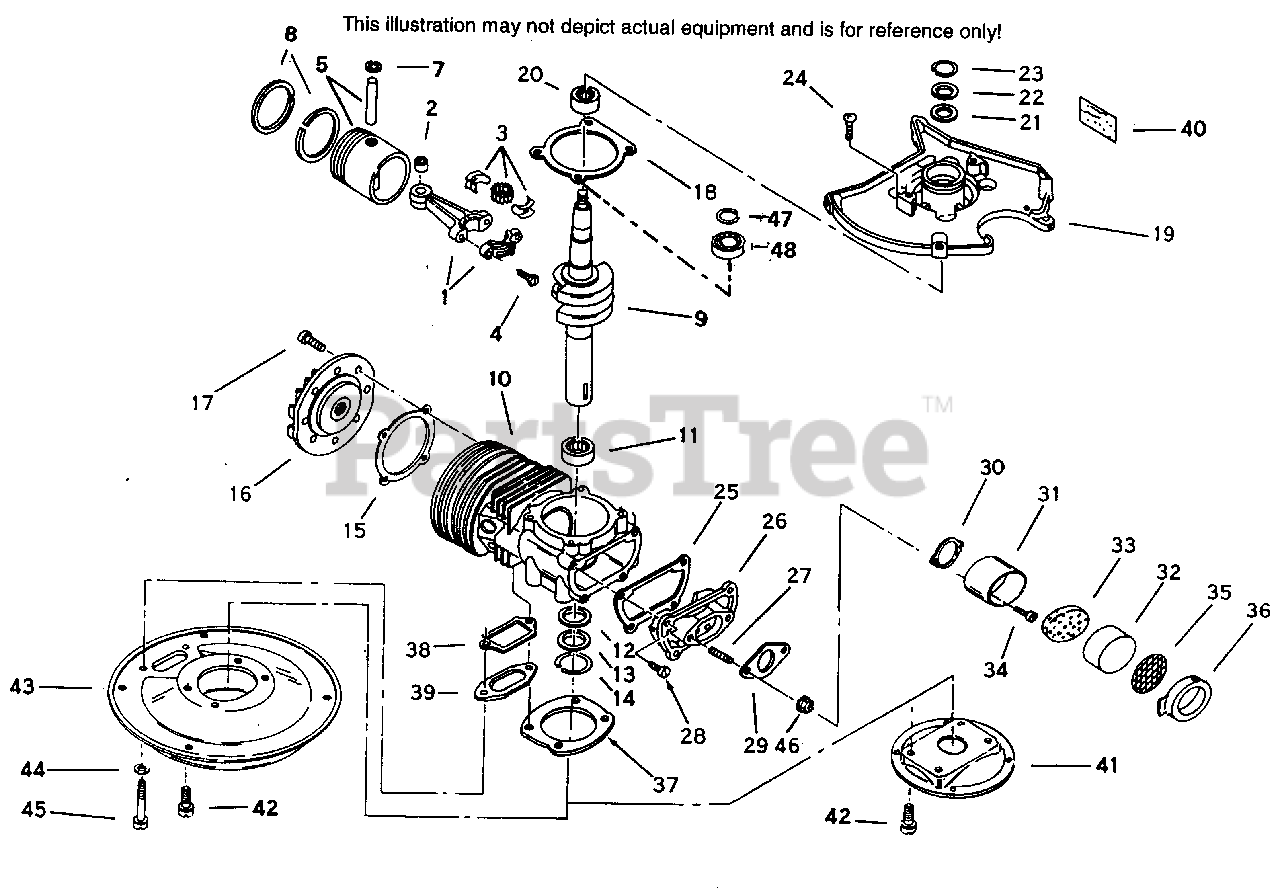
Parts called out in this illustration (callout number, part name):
1	"Rod Assy., Connecting Incl. 2, 3 & 4
2	Bearing, Needle
3	Bearing & Liner Set, Needle
4	Screw, Connecting rod
5	Piston & Pin Assy. (Incl. 7)
7	Ring, Piston pin retaining
8	Ring Set, Piston
9	Crankshaft
10	Cylinder (Incl. 11 thru 14)
11	Bearing, Needle
12	Seal Crankshaft
13	Retainer, Crankshaft seal
14	Ring, Crankshaft seal retainer
15	Gasket, Cylinder head
16	Head, Cylinder
17	Screw, Torx T-30, 1/4-20 x 3/4"
18	Gasket, Housing base
19	Blower Housing Base
20	Bearing, Needle
21	Seal Crankshaft
22	Retainer, Crankshaft seal
23	Spring, Crankshaft seal retainer
24	Screw, Torx T-30, 1/4-20 x 5/8"
25	Gasket, Reed plate
26	Plate Assy., Reed (Incl. 27)
27	Stud, Carburetor
28	Screw, Torx T-25, 10-24 x 1/2"
29	Gasket, Carburetor
30	Gasket, Air filter
31	Body, Air filter
32	Air Filter
33	Air Filter
34	Screw, Torx T-25, 10-32 x 5/8"
35	Air Filter
36	Cover, Air filter
37	Gasket, Flange
46	Nut, Flange whiz-lock, 1/4-20
46	Nut, Flange whiz-lock, 1/4-28 Use asr eq.
47	Ring, Retaining (Used on early produc tion)
